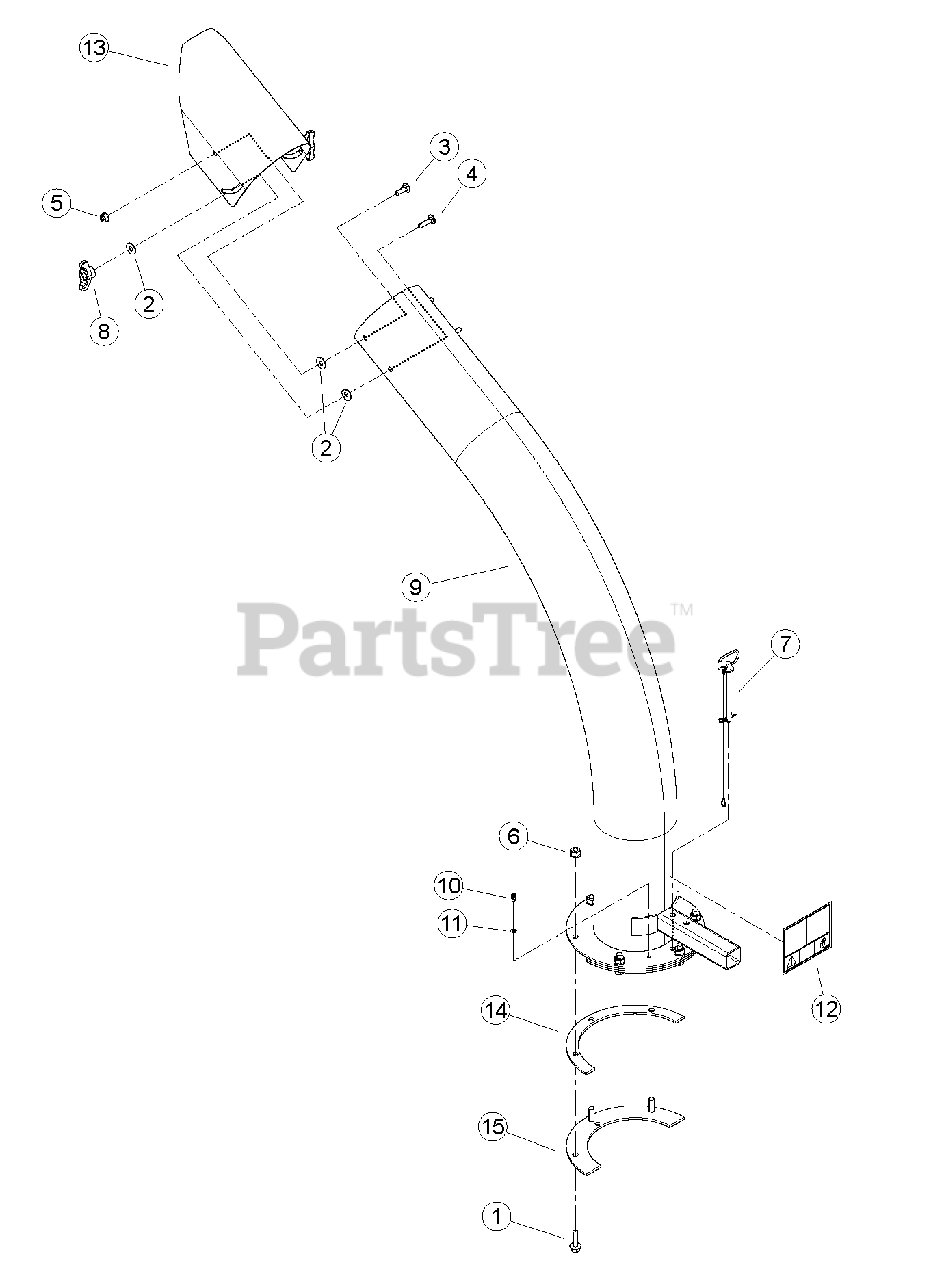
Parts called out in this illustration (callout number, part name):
1	BOLT, 3/8 X 1-1/4 FLANGE NC
2	WASHER, 5/16" FLAT ZP
3	BOLT, 5/16" X 1" GR5 CRG ZP
4	BOLT, 5/16 X 1-1/4" GR5 ZP CRG
5	NUT, 5/16-18 NYLOCK-FLANGE
6	NUT, 3/8-16 NYLOCK-FLANGE
7	PIN, 3/8 X 4.25" DISCHARGE
8	KNOB, 5/16-18 UNC TEE W/ LOCKING INSERT
9	ASSEMBLY, 6 INCH DISCHARGE CHUTE
10	FITTING, 1/4 SELF-TAP GREASE
11	WASHER, FLAT .254 X .400 X .048
12	DECAL, DISCHARGE DEBRIS & LOCK
13	DEFLECTOR, BLOWER VAC DISCHARGE
14	SPACER, DISCHARGE PIVOT
15	RING, DISCHARGE CLAMP
